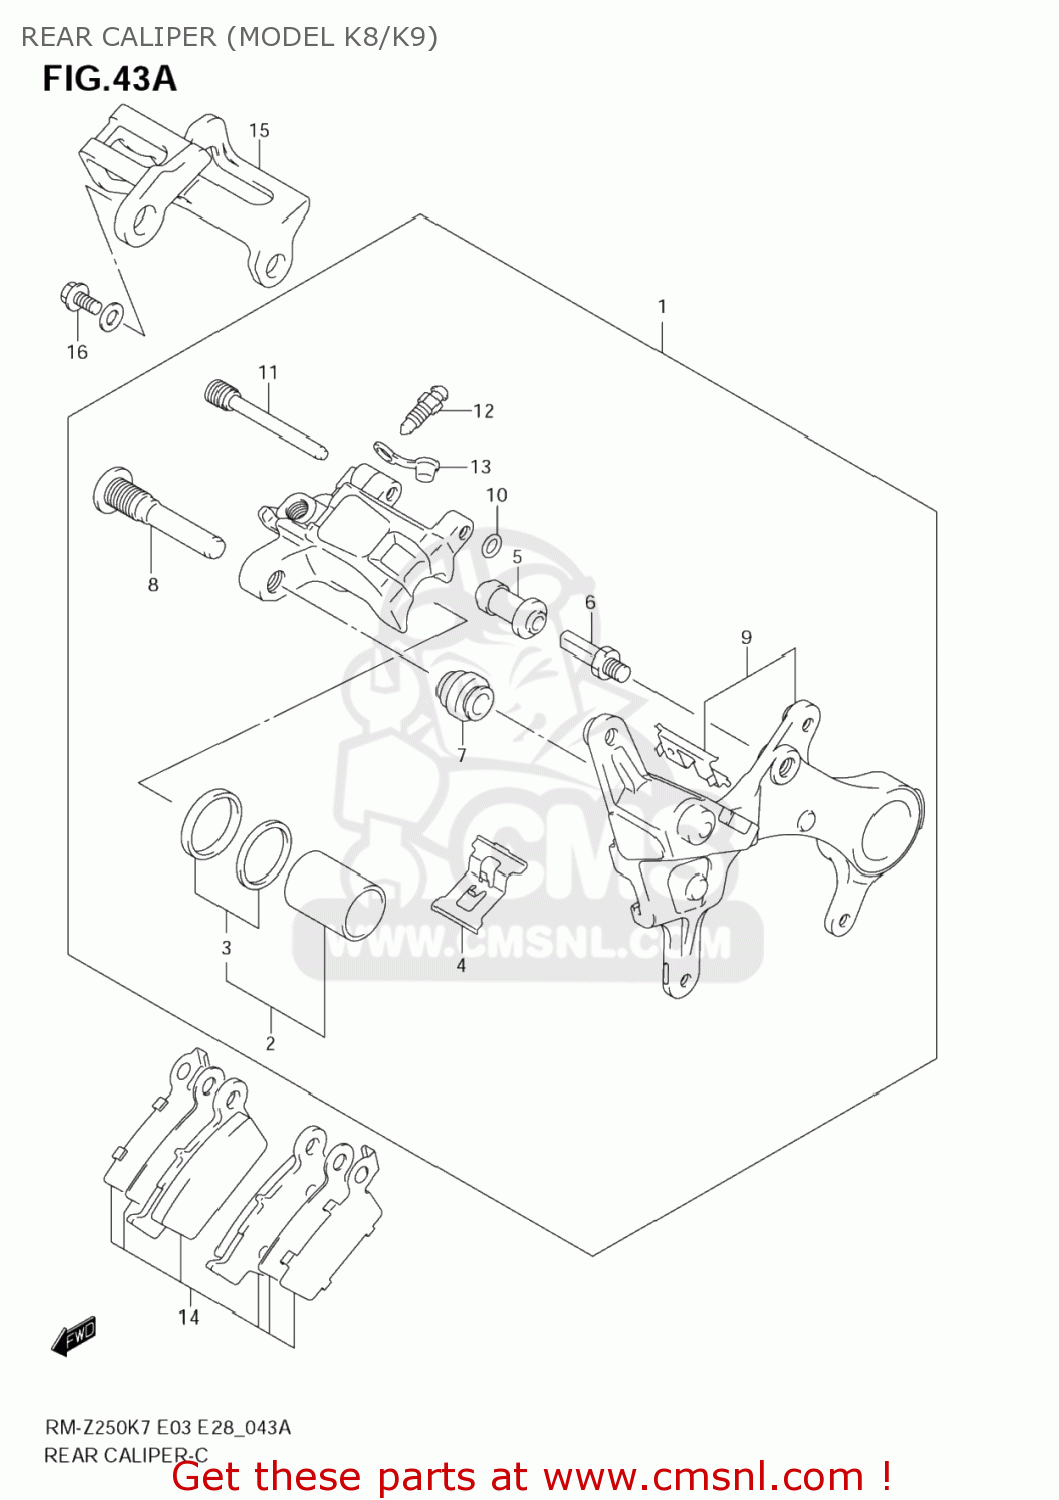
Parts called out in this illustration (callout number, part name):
1	CALIPER ASSY,RR
2	PISTON SET
3	SEAL SET,PISTON
4	SPRING,PAD
5	BOOT
6	PIN,BOLT
7	BOOT
8	PIN,BOLT
9	BRACKET
10	RING,STOPPER
11	PIN,HANGER
12	BLEEDER
13	CAP,BLEEDER
14	PAD & SHIM SET (NAS)
15	GUARD,RR CALIP
16	BOLT(6X12)
